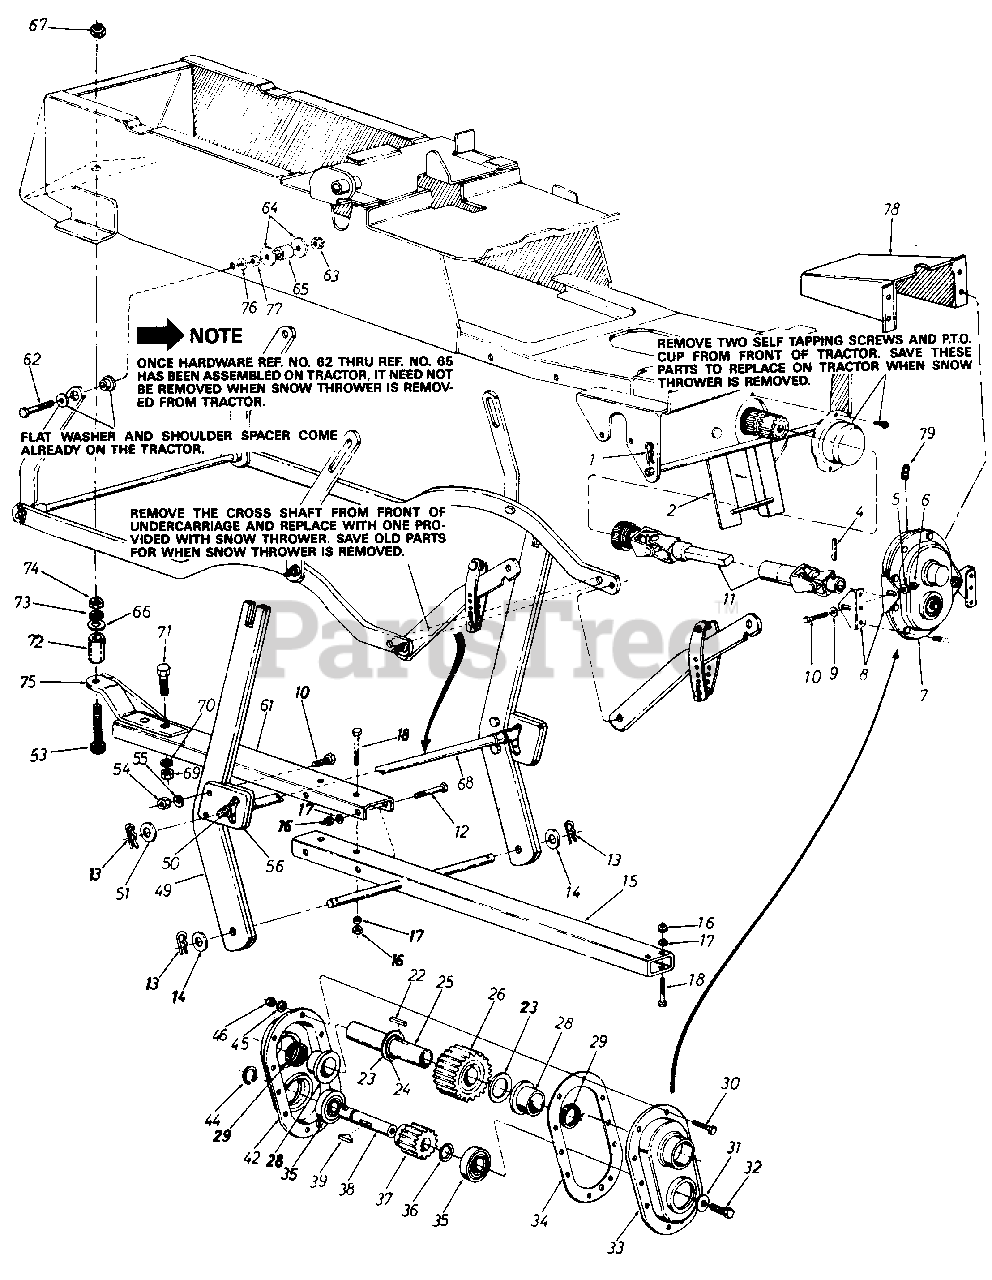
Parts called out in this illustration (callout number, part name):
1	Intern. Cotter Pin 3/4" Dia.
2	Guide Bracket Ass'y.
4	Roll Pin Spirol 5/16" Dia. x 2.5" Lg.
5	Belleville Wash. .341" I.D. x .88" O.D.
6	Hex Nut 5/16-18 Thd.4
7	Gear Box Ass'y. Comp.
8	Gear Box Support Brkt.
9	Belleville Wash. .341" I.D. x .88" O.D.
10	Hex Bolt 5/16-18 x 1.25" Lg. (Grade 5)
11	Universal Drive Shaft Ass'y.
12	Hex Bolt 3/8-24 x 4.50" Lg.*
13	Hair Pin Cotter
14	Fl.-Wash. .75" i.D. x 1.5" O.D.
15	Lift Shaft Ass'y.
16	Hex Ins. Jam L.-Nut 3/8-24 Thd.
17	L.-Wash. 3/8" I.D.*
18	Hex Bolt 3/8-24 x 2.75" Lg.
22	Hi-Pro Key 1/4" x 7/8" Dia.
23	Fl.-Wash. 1.31" I.D. x 2.00" O.D. x .060
24	Snap Ring for 1.25" Dia. Shaft
25	Gear Shaft 1.25" Dia. x 6.0" Lg.
26	28 Teeth Spur Gear
28	Flange Bearing 1.25" I.D. x 1.75" O.D.
29	Oil Seal 1.25" I.D. x 1.75" O.D. x .26
30	Hex Bolt 1/4-28 x .88" 4.
31	Fl.-Wash. .40" I.D. x 1.25" O.D. x .160
32	Hex L.-Bolt 3/8-24 x 1.00" Lg.
33	Gea; Housing Half - L.H.
34	Gasket
35	Ball Bearing 1.00" I.D. x 2.00" O.D.
36	Fl.-Wash. 1.03" I.D. x 1.63" x .090
37	15 Teeth Spur Gear
38	Input Shaft
39	Woodrull Key 1/4" x 3/4" Dia.
42	Gear Housing Half-R.H.
44	Snap Ring for 1.00" Dia. Shaft
45	Spring Wash. 1/4" I.D.
46	Hex Nut 1/4-28 Thd.
51	Fl.-Wash. .62" I.D. x 1.12" O.D.
53	Hex Bolt 5/8-11 x 4.00" Lc
54	Hex Nut 5/16-18 Thd.*
55	L.-Wash. 5/16" I.D.*
62	Hex Bolt 3/8-24 x 2.50" 4. (Grade 5)
63	Hex Jam L.-Nut 3/8-24 Thd.
64	Fl.-Wash. .375" I.D. x 1.00" O.D. x .135"
65	Spacer.375" I.D. x .625" O.D. x .445
66	Fl.-Wash. .62" I.D. x 1.12" O.D.
67	Hex Jam L.-Nut 5/8-11 Thd.
68	Cross Shaft Ass'y.
69	Hex Nut 1/2 -13 Thd.*
70	L.-Wash. 1/2" I.D.*
71	Hex Bolt 1/2-13 x 1.25" Lg.
72	Spacer.65" I.D. x 2.12" Lg.
73	L.-Wash. 5/8" I.D.*
74	Hex Jam Nut 5/8-11Thd.
77	Hex Nut 3/8-24 Thd.*
78	Drive Shaft Cover
79	Grease Fitting
